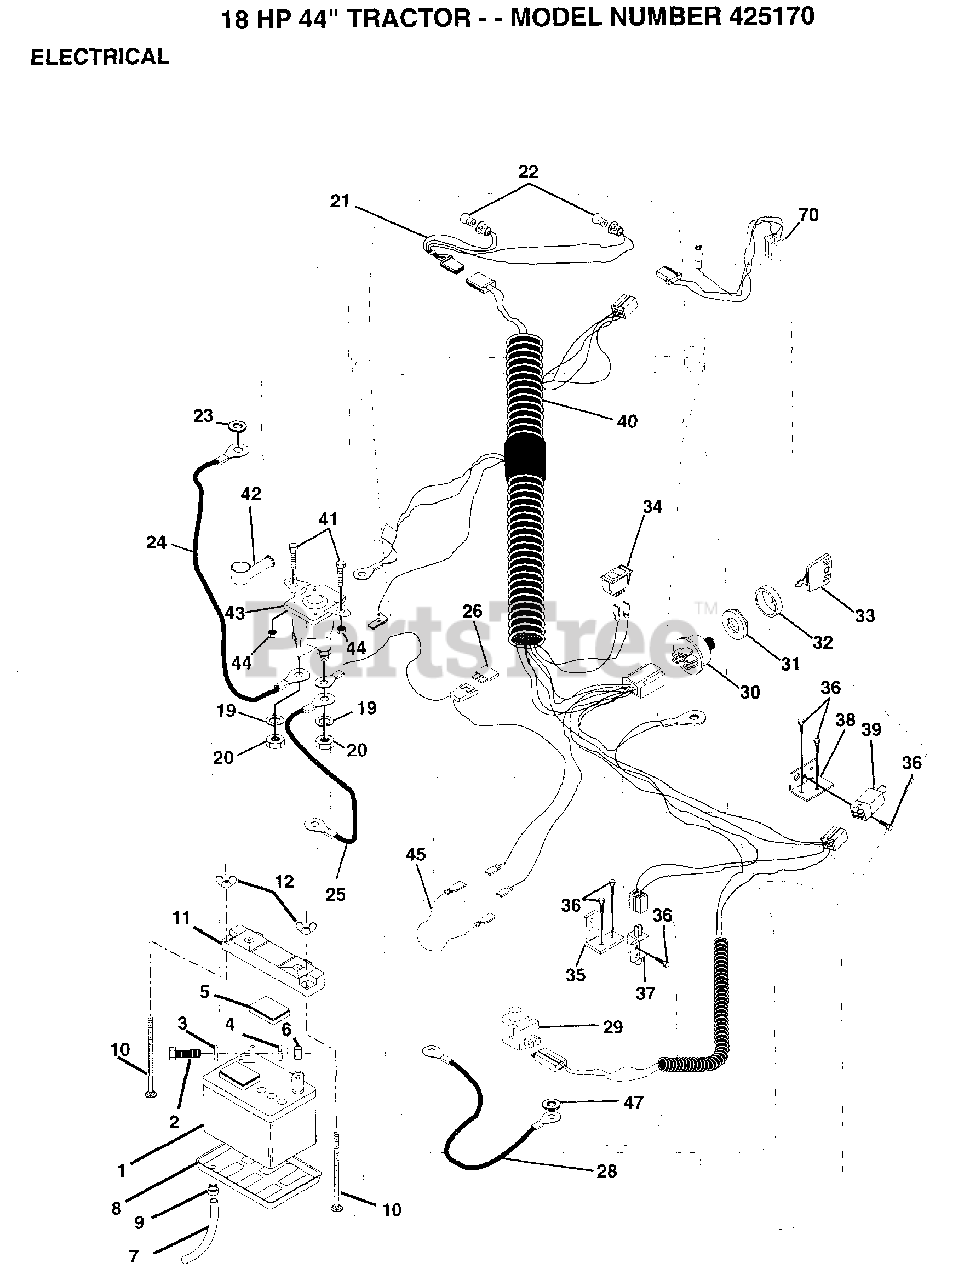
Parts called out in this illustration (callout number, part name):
2	BOLT LT
3	WASHER
4	LOCKWASHER
5	"CAP,BATTERY "
7	"DRAIN TU T, BATT"
8	"TRAY T, BATTERY"
9	HOSE CLAMP T
10	BOLT
20	NUT
21	"HARNESS,LIGHT SOC"
22	HEADLAMP BULB
23	LOCKWASHER
24	"CABLE T, BATTERY"
25	CABLE-BATTERY T
26	FUSE HYT
28	CABLE T
29	SWITCH SEAT
32	COVER KEY SWITCH
33	KEY MLD GEN DELTA
34	SWITCH LT
35	BRACKET LT
36	SCREW
37	SWITCH-INTER. GT
38	BRACKET SWITCH IN
39	SWITCH INTERLOCKT
40	HARNESS.IGN.DASH
41	BOLT HXHD FIN
44	NUT HXKEP 1/4X20
45	ADAPTER AMMETER
47	LOCKWASHER
70	HARNESS ENG DUAL
